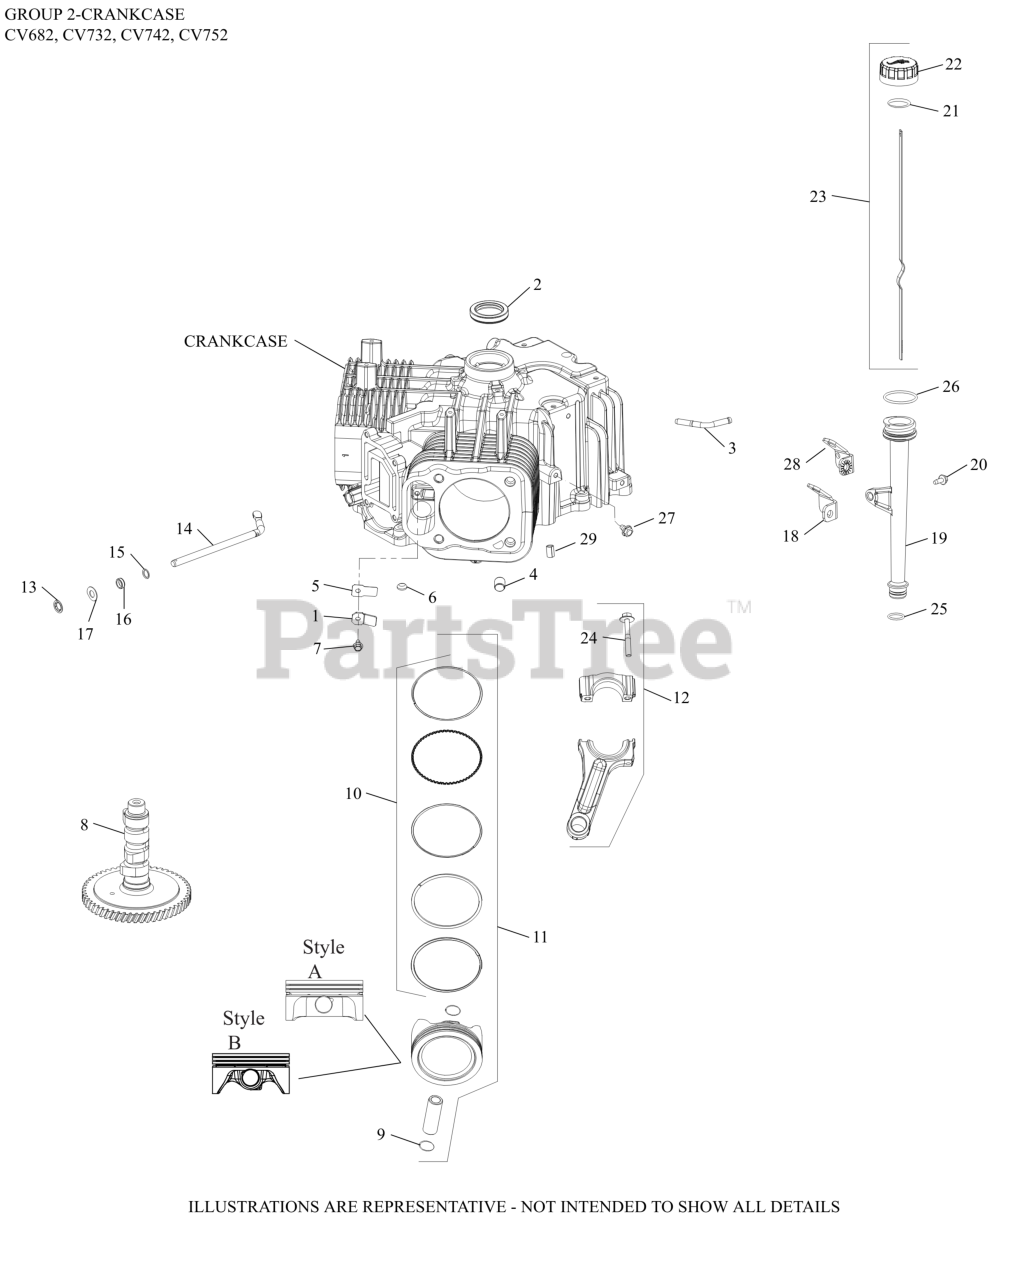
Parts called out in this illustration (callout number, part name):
1	RETAINER, BREATHER REED
2	SEAL, OIL (HELIX LIP)
4	PIN, LOCATING
5	REED, BREATHER-(#2440207S)
6	PLUG, CUP
7	SCREW, FLG THD FRM M5X.8X10
8	KIT, CAMSHAFT
9	RETAINER, PISTON PIN
10	RING DISC USE PISTON ASSY PER SPEC
10	RING SET(.08)STYLE A-1.5mm Tp RING THICK
10	RING SET(.50)STYLE A-1.5mm Tp-(#DSC)
10	RING SET(STD)STYLE B-1.2mm Tp RING THICK
10	RING SET(.08)STYLE B-1.2mm RING THICK
10	RING SET(.25)STYLE B-1.2mm Tp RING THICK
10	RING SET(.50)STYLE B-1.2mm Tp RING THICK
11	KIT,PSTN/RNG STYLE A(STD)(#2587406S)
11	KIT,PSTN/RNG STYLE A(.08)
11	KIT,PSTN/RNG STYLE A(.25)USE 2587411-S
11	KIT,PSTN/RNG STYLE A(.50)(#2587404S)
11	KIT,PSTN/RNG STYLE B(STD)
11	KIT,PSTN/RNG STYLE B(.08)
11	KIT,PSTN/RNG STYLE B(.25)
11	KIT,PSTN/RNG STYLE B(.50)
12	ROD, ASSEMBLY CONNECTING
13	RETAINER, RING
14	SHAFT, GOVERNOR CROSS
15	WASHER, FLAT 11/32"
16	SEAL, GOVERNOR CROSS SHAFT
17	WASHER, FLAT 9 MM
19	TUBE ASSEMBLY
20	SCREW, FLG THD FRM M5X0.8X13
21	O-RING, DIPSTICK
22	KIT, OIL FILL CAP (YELLOW)
23	DIPSTICK, ASSY
24	KIT, ROD BOLTS-(#25086677S)
25	O-RING, LOWER OIL FILL TUBE
26	O-RING, UPPER OIL FILL TUBE
NI	BRACKET, OIL FILL TUBE
NI	SCREW, THREAD FORMING
